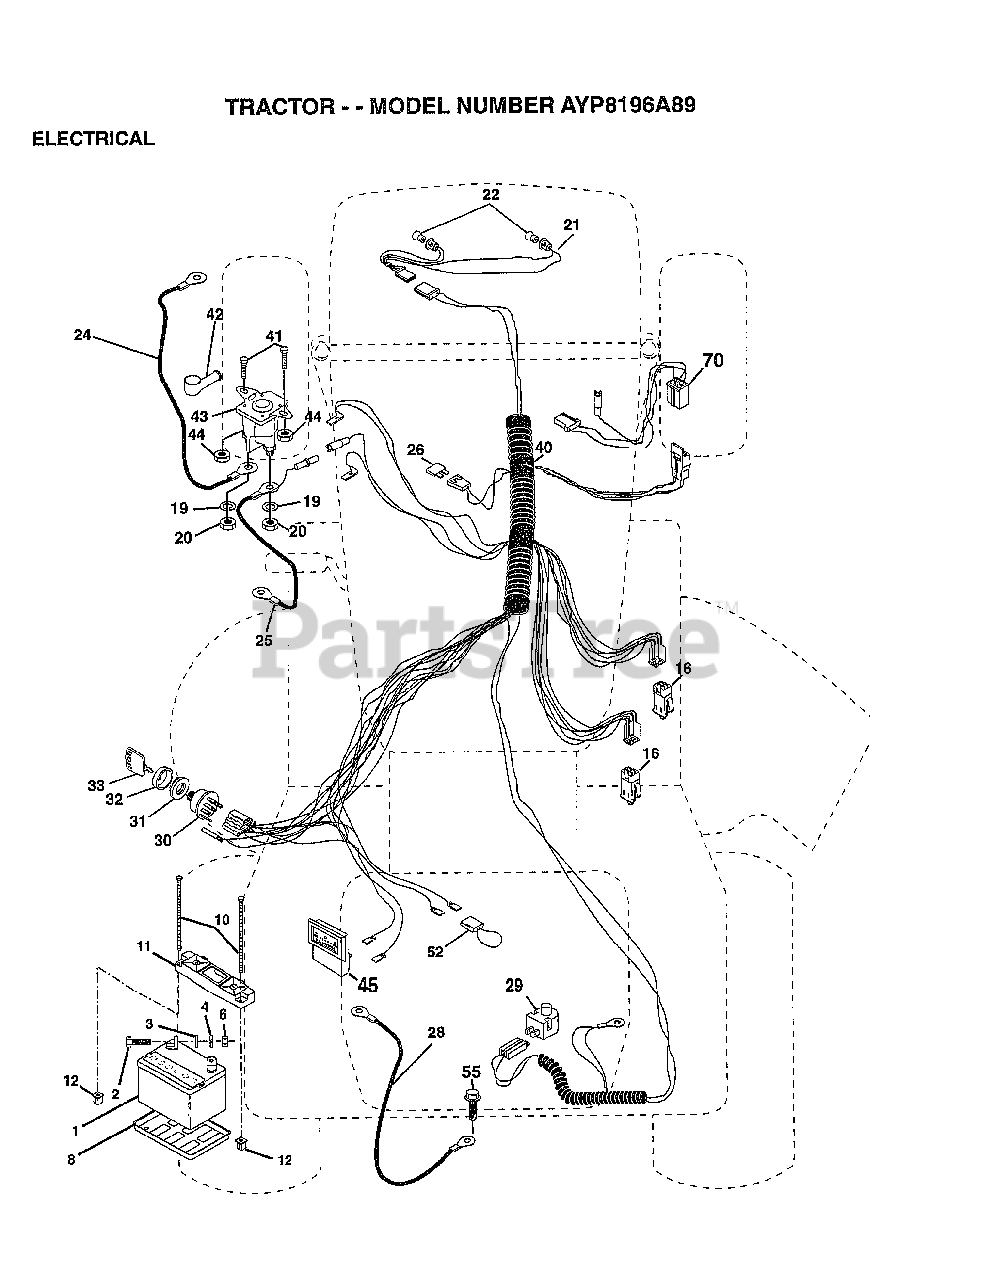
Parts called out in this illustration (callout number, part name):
3	WASHER
4	LOCKWASHER
8	"TRAY T, BATTERY"
11	HOLDDOWN BATTERY
16	SWITCH INTERLOCK
20	NUT
21	"HARNESS,LIGHT SOC"
22	HEADLAMP BULB
24	"CABLE T, BATTERY"
25	CABLE.6GA.22W/16W
26	FUSE HYT
28	CABLE.GRND.6GA.21
29	SWITCH SEAT
30	SWITCH IGN 4POS
31	NUT IGNITION
32	COVER KEY SWITCH
33	KEY
40	HARNESS-IGNITION
41	BOLT HXHD FIN
44	NUT HXKEP 1/4X20
52	PROTECTION LOOP
70	HARNESS ENG DUAL
